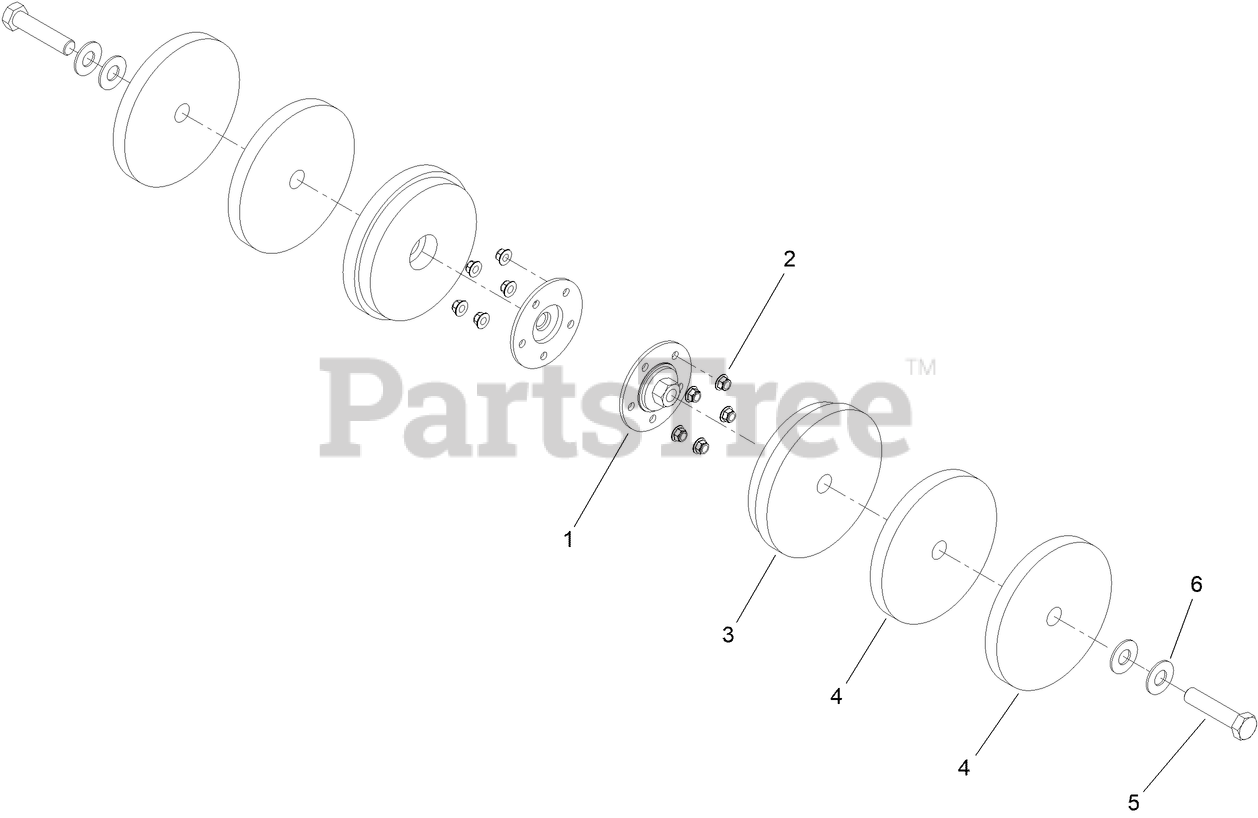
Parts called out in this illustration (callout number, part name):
1	PLATE - RETAINER DUAL WHEEL
2	NUT-HHF
3	INNER WEIGHT (WELDMENT)
4	PLATE-WHEEL WEIGHT
6	WASHER-FLAT
